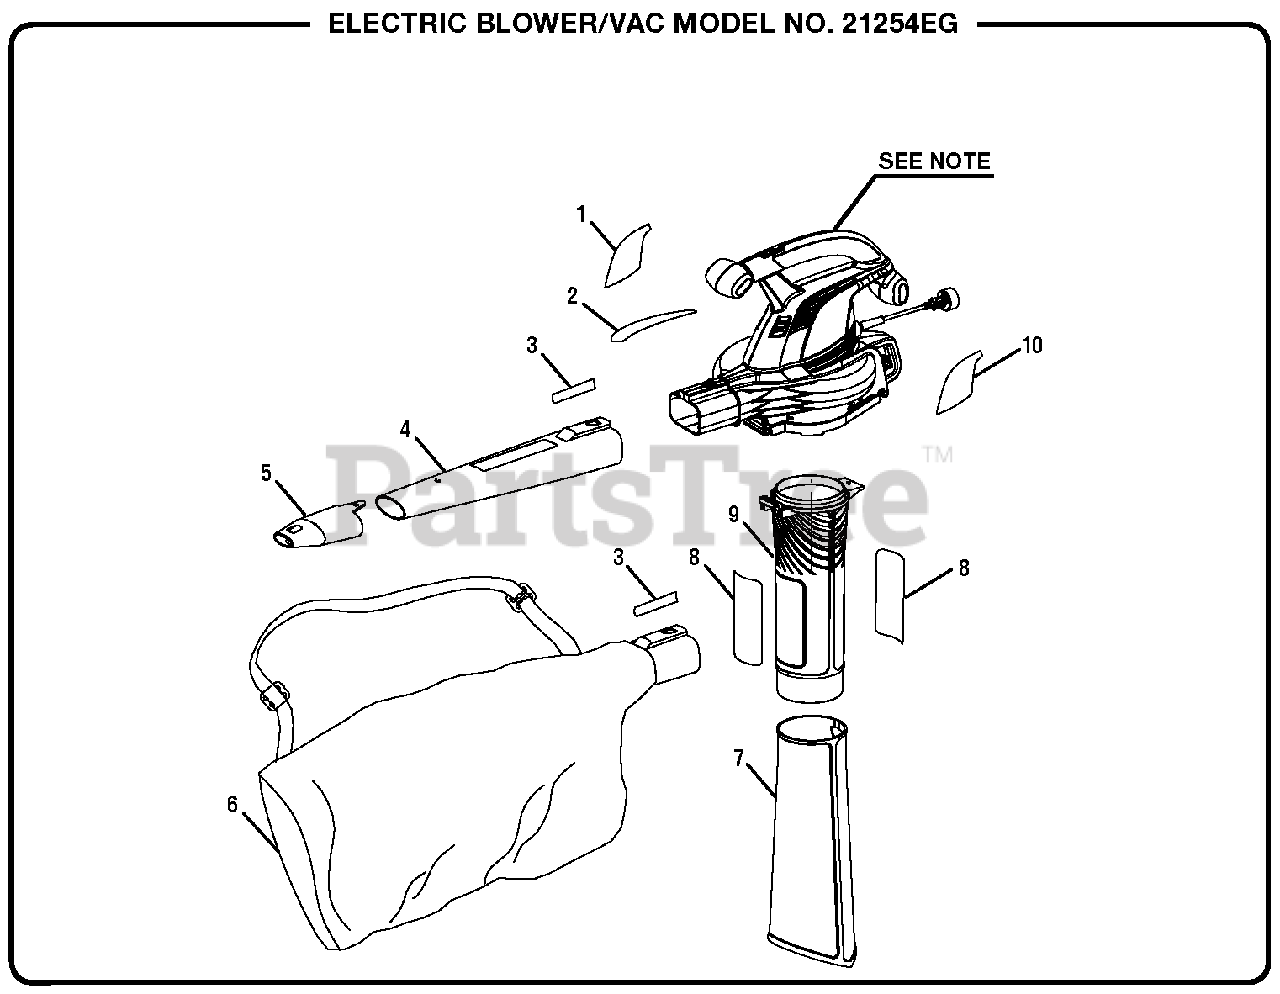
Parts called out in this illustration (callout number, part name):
1	Logo Label (Motor Housing)
2	Warning Icon/Performance Label
3	Caution Label (Blower Tube & Vacuum bag)
4	Blower Tube
5	High Velocity Nozzle
6	Vacuum Bag
7	Lower Vacuum Tube
8	Logo Label (Upper Vacuum Tube)
9	Upper Vacuum Tube
10	Data Label
